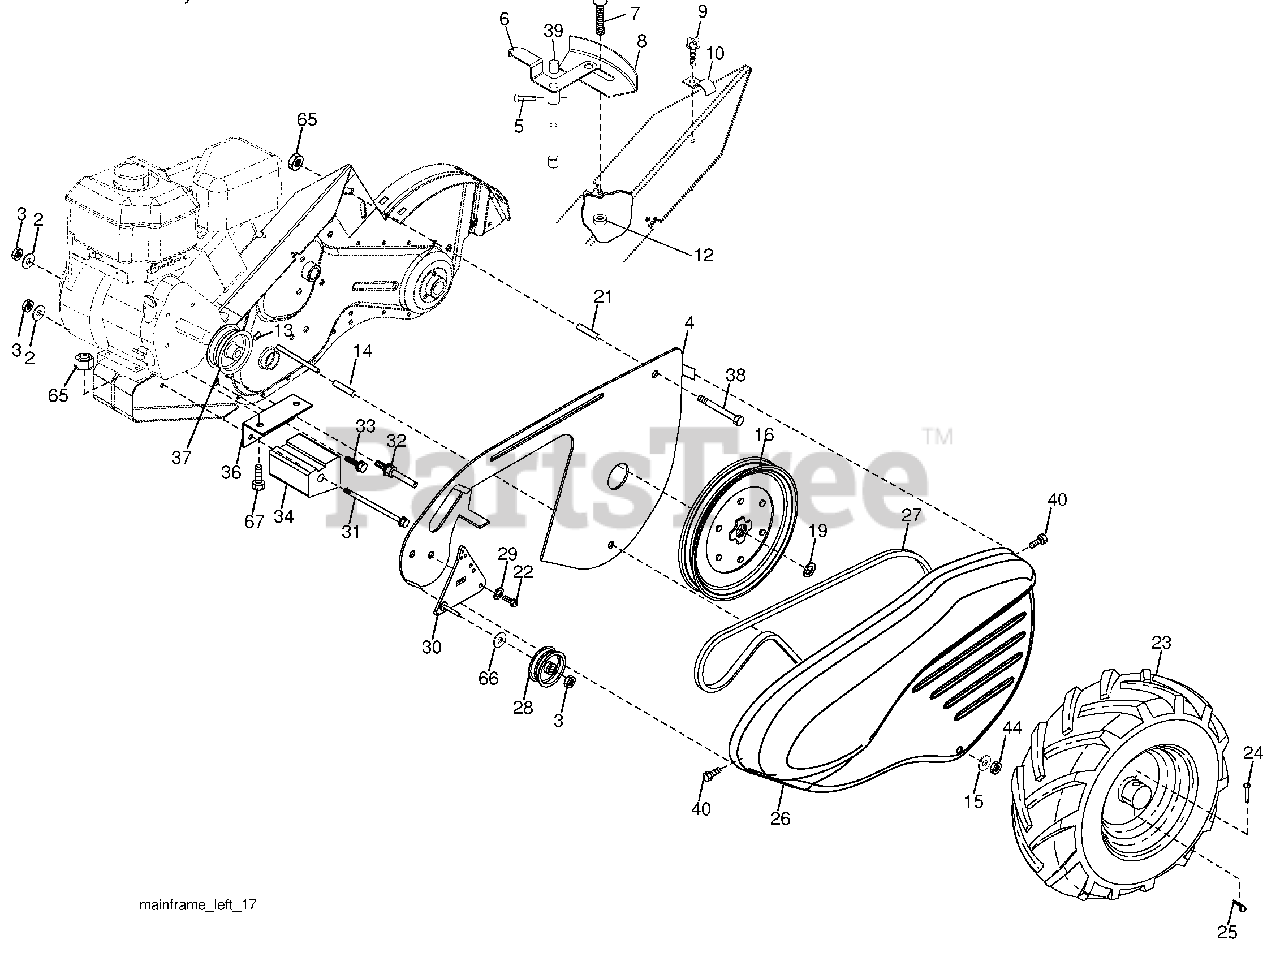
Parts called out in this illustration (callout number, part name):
1	Nut, Hex, Flanged 5/16-18
2	Washer, Lock 3/8
3	Nut, Hex 3/8-16
4	Shield, Inner Belt Guard RT
5	Screw, Shift Lever
6	Lever, Shift
7	Bolt, Carriage 1/4-20 x 1/2 Gr. 5
8	Plate, Shift Indicator
9	Screw, Hex, Washer Head, Slotted #10-24 x 1/2
10	Clip
12	Nut, Keps Hex 1/4-20 unc
13	Screw, Set, Hex 5/16-18 x 3/8
14	Spacer, Split 0.327 x 0.42 x 1.220
15	Washer 11/32 x 11/16 x 16 Ga.
16	Sheave, Transmission
19	Retainer, Ring
21	Spacer, Split 0.327 x 0.42 x 2.09
22	Bolt, Fin Hex 5/16-24 UNF x 1/2
23	Tire
23	Rim
23	Tire Valve
24	Rivet, Drilled
25	Clip, Hairpin
27	Belt, V
28	Pulley, Idler
29	Ring, Klip
30	Bracket, Idler
31	Bolt, Hex 5/16-16 x 12
32	Shaft, Idler Arm
33	Bolt, Hex 3/8-16 x 1
34	Counterweight, L. H.
35	Bolt, Hex 5/16-18 x 1-3/4
36	Bracket, Reinforcement, L. H.
37	Sheave, Engine
38	Bolt, Fin Hex 5/16-18 unc x 2-3/4
39	Cap, Plunger Blk
40	Screw Hex Wsh Slt #10-24 x 1/2
44	Nut Lock Hex w/Ins 5/16-18 unc PL
65	Nut Lock Hex Flange
66	Washer 13/32 x 13/16 x 12 Ga.
